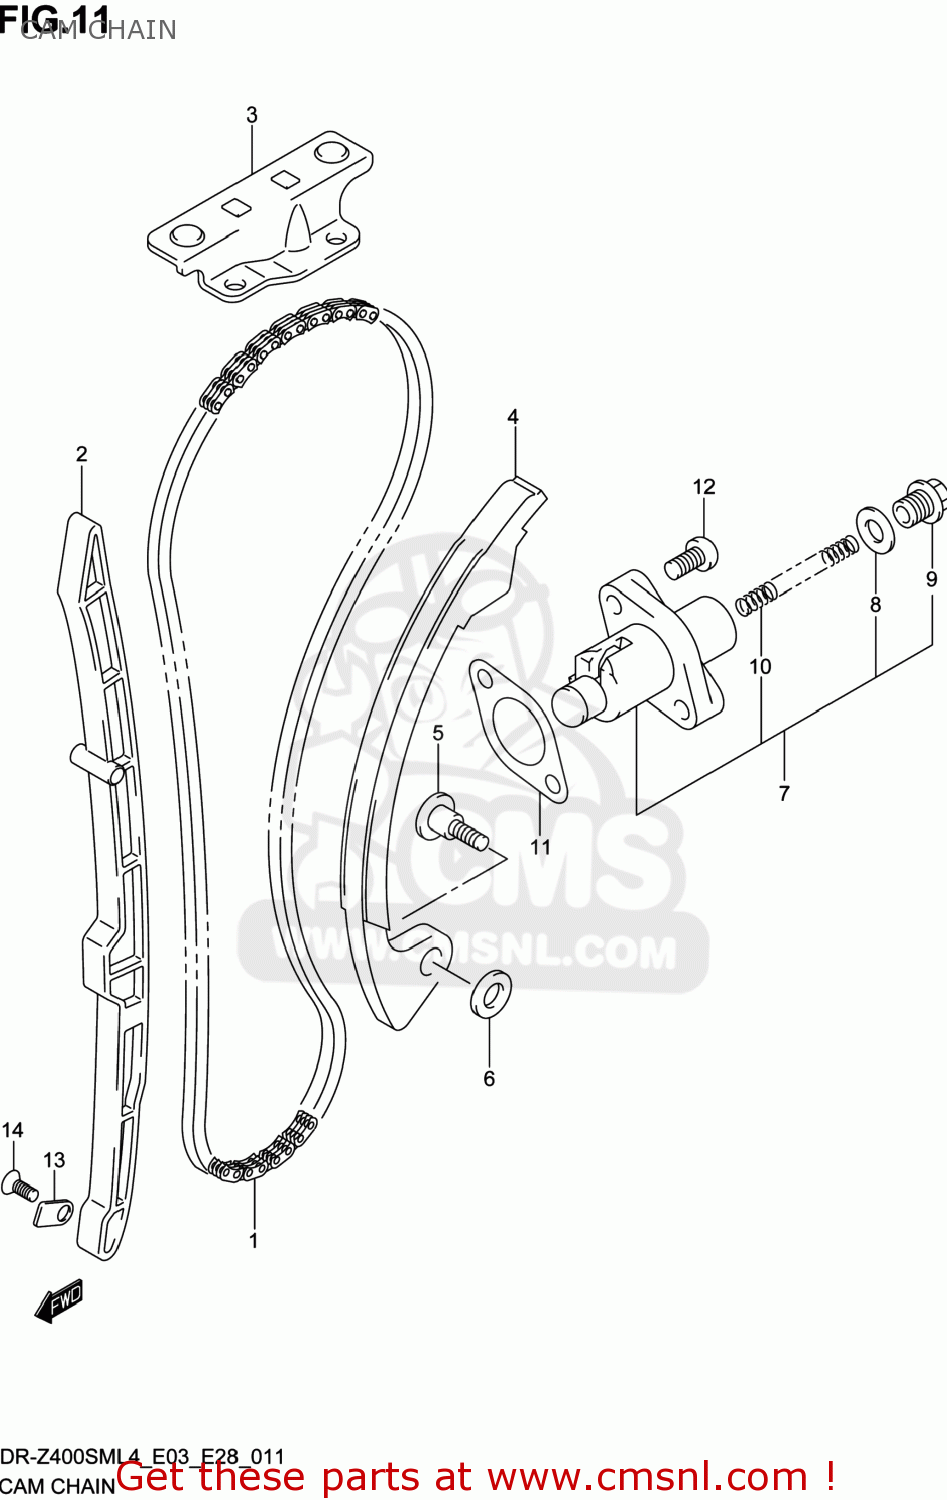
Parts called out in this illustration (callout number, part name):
1	CHAIN,CAMSHAFT DRIVE
2	GUIDE,CAM CHAIN NO.1
3	GUIDE,CAM CHAIN NO.2
4	TENSIONER,CAM CHAIN
5	BOLT,CAM CHAIN TENSIONER
6	WASHER
7	ADJUSTER ASSY,TENSIONER
8	GASKET,TENSIONER ADJUSTER (NAS)
9	PLUG,FR TENSIONER ADJ
10	SPRING
11	GASKET,TENSIONER ADJUSTER (NAS)
12	BOLT
13	RETAINER,CAM CHAIN GUIDE NO.1
14	SCREW(6X12)
